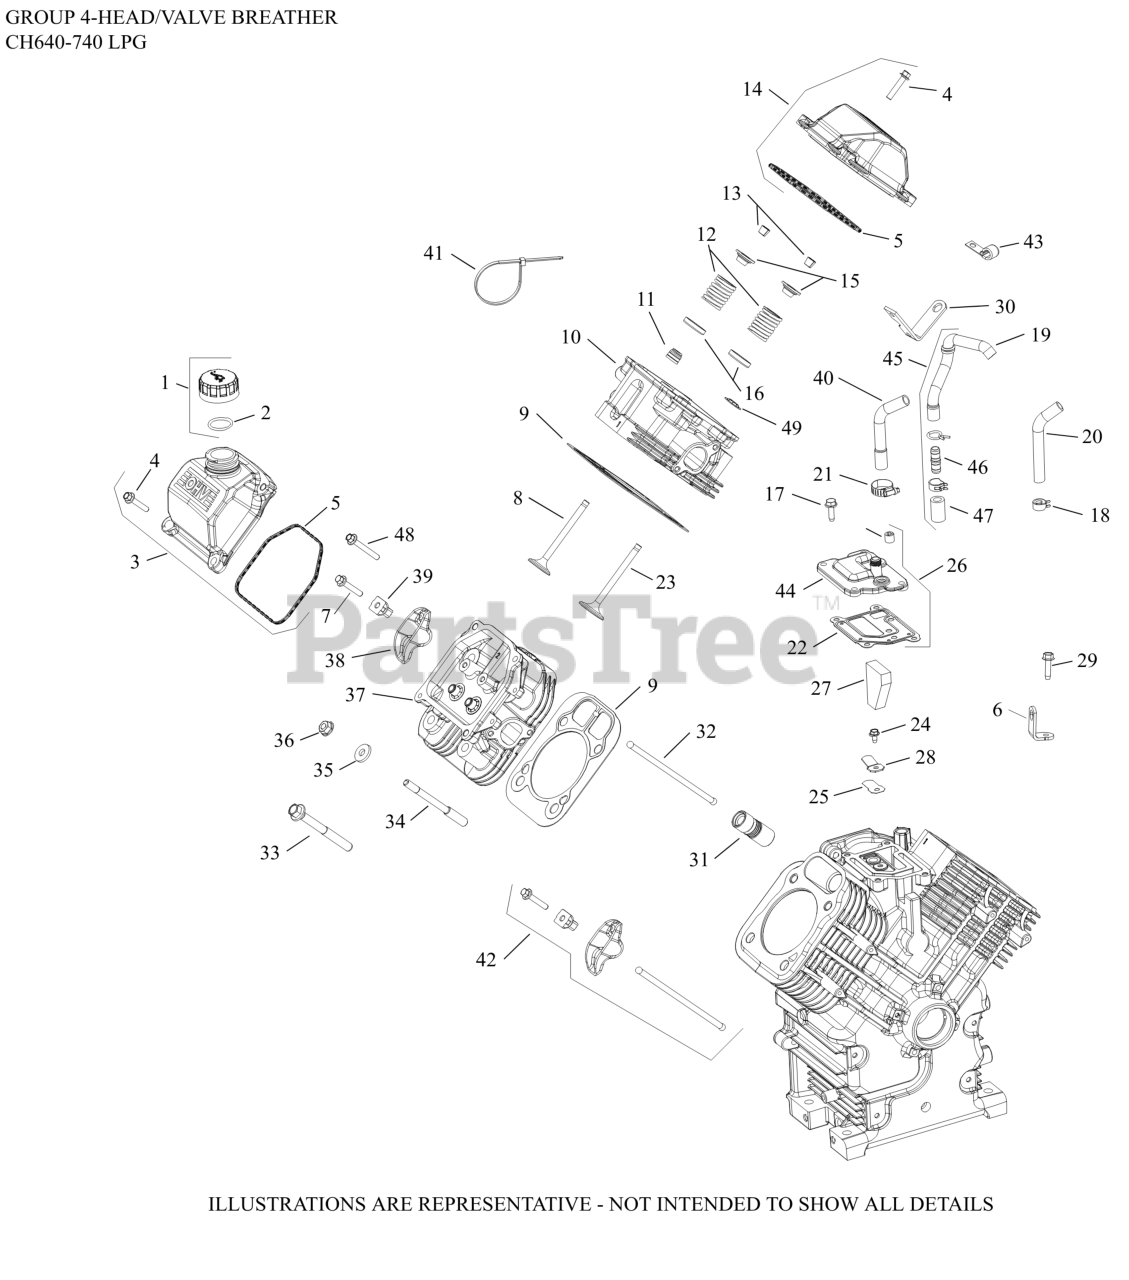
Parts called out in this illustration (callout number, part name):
1	KIT, OIL FILL CAP (YELLOW)
2	O-RING, DIPSTICK
3	KIT, VALVE COVER-OIL FILL
4	SCREW, FLG M6X1.0X30
5	O-RING (YELLOW), VALVE CO
7	SCREW, FLG (BLACK) M6X1.0X34
8	VALVE, EXHAUST
8	VALVE, EXHAUST (.25)
9	KIT, GASKET CYLINDER HEAD
10	KIT, CYLINDER HEAD-(#24318206S)
11	SEAL, VALVE BAND
12	SPRING, VALVE
13	KIT, RETAINER
14	KIT, VALVE COVER-PLAIN (PLASTIC)
15	CAP, VALVE SPRING
16	RETAINER, SPRING
18	SPRING CLAMP, HOSE
22	GASKET, BREATHER
23	VALVE, INTAKE (STD)
23	VALVE, INTAKE (.25)
24	SCREW, FLG THD FRM M5X.8X10
25	REED, BREATHER-(#2440206S)
25	REED, BREATHER
27	FILTER, BREATHER
28	RETAINER, REED
29	SCREW, THREAD FORMING
30	STRAP, LIFT
31	LIFTER, VALVE HYDRAULIC-USE 25 351 11-S
32	ROD, PUSH
34	STUD, M8X1.25
35	WASHER, FLAT 8.6 MM
36	NUT, FLG M8X1.25
37	KIT, CYLINDER HEAD-(#24318207S)
38	ARM, ROCKER
39	PIVOT, ROCKER ARM
40	HOSE, BREATHER
42	KIT, VALVE TRAIN
44	COVER, BREATHER
NI	RETAINER, VALVE GUIDE (KM)
NI	SCREW, THREAD FORMING
